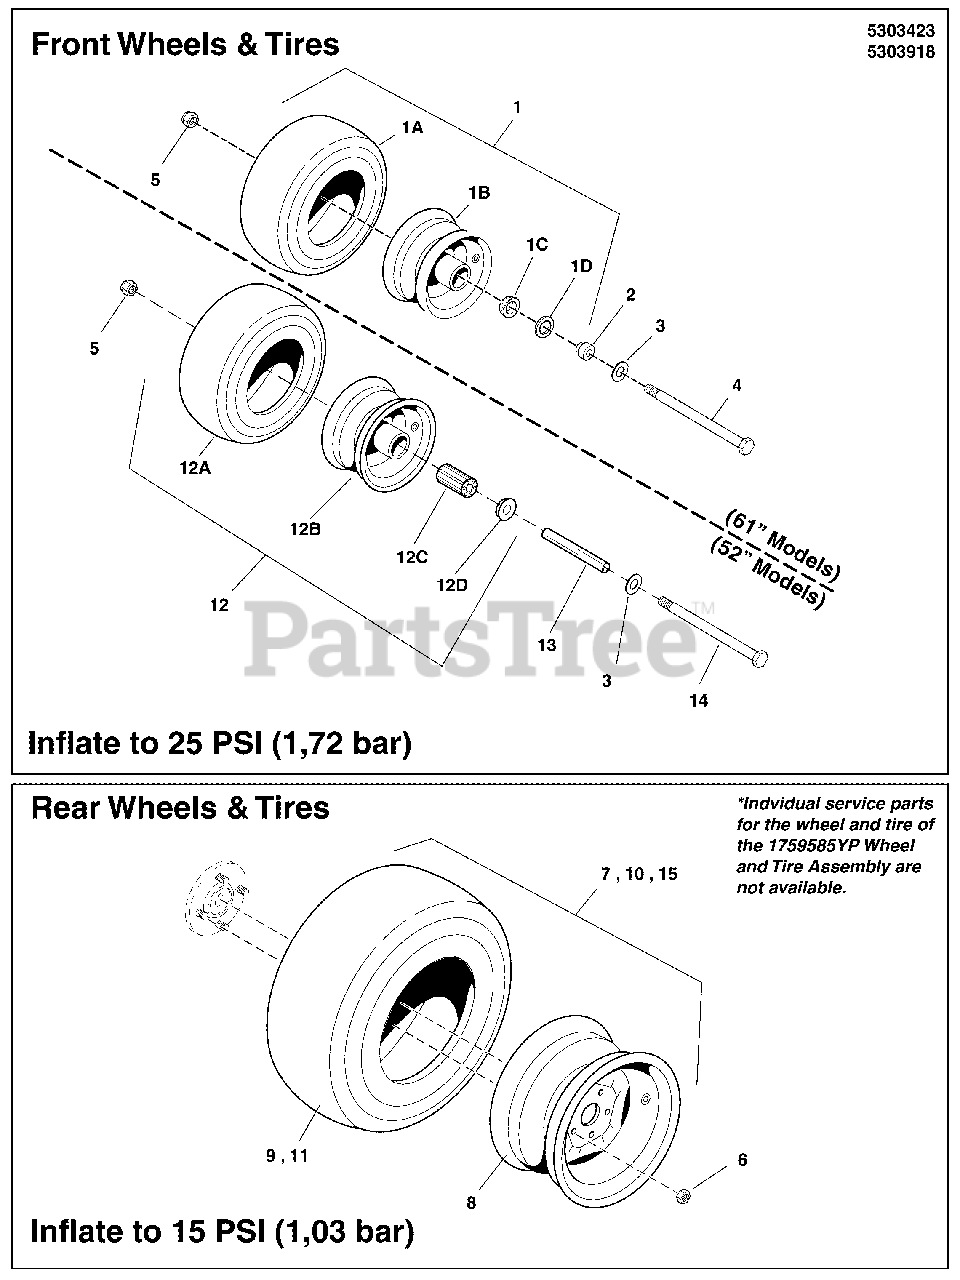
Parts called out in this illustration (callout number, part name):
1	TIRE, CASTER, 13 X 5.00-6
1A	TIRE ONLY (SV)
1B	WHEEL ASSY, 13 X 5 X 6, SILVER (SV)
1C	BEARING, TAPERED CONE
1D	SEAL, GREASE
2	ADAPTER, CASTER AXLE, CZ
3	WASHER, 1/2 SAE
4	BOLT, 1/2-13 X 8 GD5 YZ
5	NUT, 1/2-13 HEX NYLOCK FLANGE
6	NUT, 1/2-20, FOR WHEEL BOLT SILVER
7	TIRE/WHEEL ASM, 20X 10-8, TURF MASTER
8	WHEEL, 8 X 6.331.29" NEG OFFSET, 4/4 BOLT PATTERN (SV)
9	TIRE, 20 X 10 - 8, TURF MASTER (SV)
10	TIRE ASSM, 20X10.00-8, TURF TRAC
11	TIRE, 20X10-8, TURF TRAC, 4 PLY
12	WHEEL ASSEMBLY, Caster, 11 X 4.0 - 5
12A	TIRE, Caster, 11 X 4.0 - 5 (SV)
12B	RIM, Caster , 11 X 4.0 - 5
12C	BEARING, CASTER WHEEL, 11 X 4.0 - 5 BEAD LOCK
12D	RETAINER, Bearing
13	AXLE, Caster
14	BOLT, 1/2-13 X 7 GD5 CZ
15	WHEEL AND TIRE ASSY, 20X10-8 (K505)
